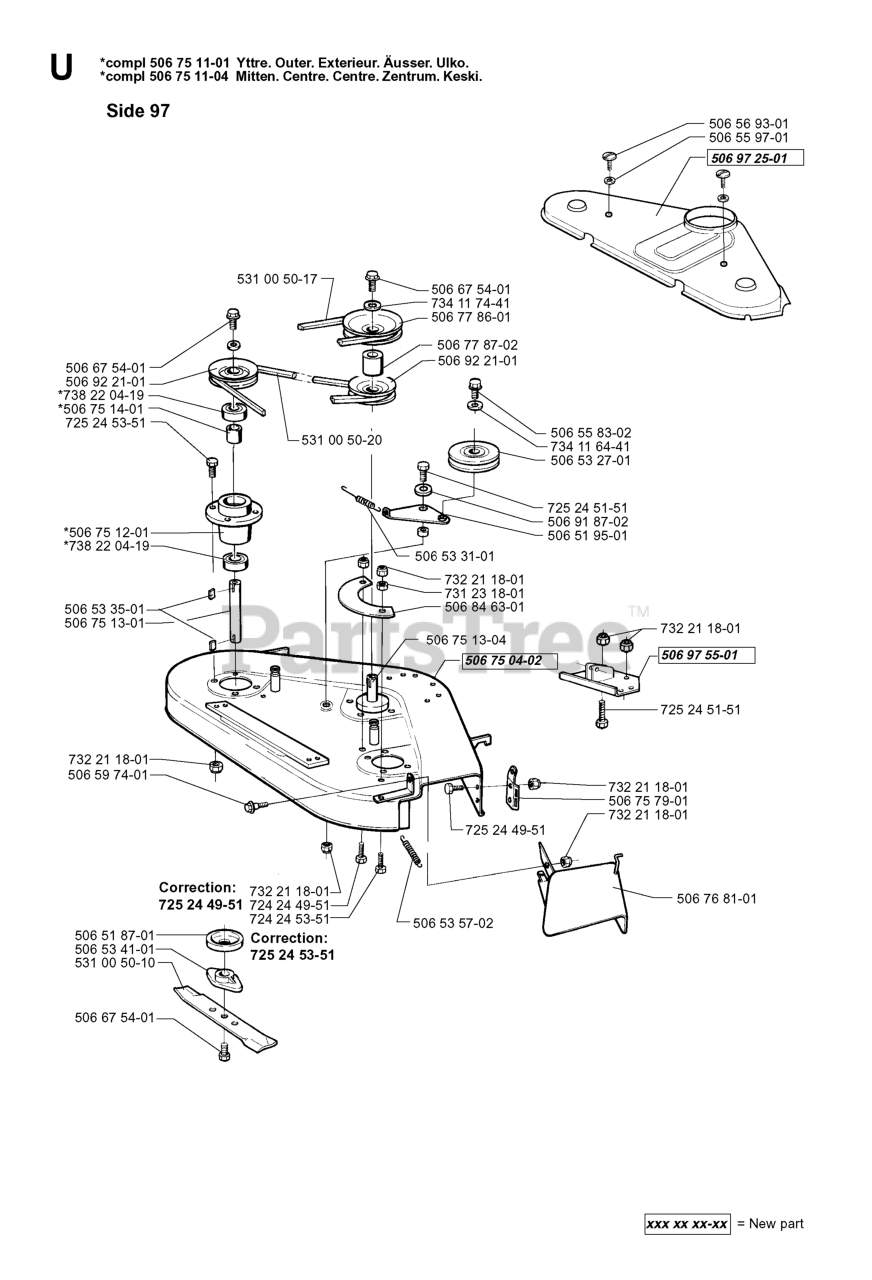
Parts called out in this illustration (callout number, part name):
1	DECK ASM MWR 50VT
2	LOCKNUT
3	BOLT.CARR.SQNK.5/16-18UNC.X3/4
4	RUNNER-LH M
5	BRACKET SWAY BAR
6	RETAINER-SPRNG RB
7	REAR SUSP ARM
8	BLADE BOLT
9	LOCKWASHER
10	WASHER.BLADE
11	BLADE.50".HI-LIFT
12	BEARING.BALL.#6204.(MANDREL)
13	SHAFT.ASM.W/BEARING
14	HOUSING.MANDREL.44/46" VENT
16	STRIPPER
17	ROD-HINGE T
18	Washer 11/32 x 5/8 x 16 Ga SD
19	CAP-SLEEVE LT
20	SPRING TORSION
21	BRACKET, DEFLECTOR
22	NUT PUSH M
23	SHIELD.DEFLECTOR.MOWER.50"BLK.
25	WASHER M
27	WASHER
28	IDLER SPRING SPACER
29	NUT
30	SCREW
31	NUT
32	PULLEY/MANDREL
33	WASHER
34	BOLT.3/8-14X1.25
36	BOLT D
37	STIFFENER ARM
38	KEEPER
39	FLAT IDLER PULLEY
40	PULLEY.DRIVEN.44"
42	RP BOLT 5/16-18 X3/4 ZN/YEL GR
43	ARM.IDLER.SEC.44"
44	SPACER RETAINER
46	BOLT
47	COVER MANDRELL
48	SCREW.1/4-20X5/8
49	COVER.MANDREL.LH.44"
50	ARM.IDLER.PRIMARY
51	SPRING.SEC.44"VEN
52	PULLEY IDLER
53	SHIELD IDLER
54	V-BELT.PRMRY 46/50 VENT.BLK BK
55	BELT V SECONDARY
57	BAR.ASM.GUAGE.WHEEL
58	WHEEL GAGE DONUT
59	BOLT, SHOULDER
60	PIN.CLEVIS
61	BRACKET.GUAGE.WHEEL
62	HARDENED WASHER
63	BOLT.3/8-16X1.50
64	WASHER.5/16.FLAT.STE.STD.
65	PULLEY IDLER FLAT
66	KEEPER
67	LOCKNUT
94	BOLT
95	BRACKET LH (A)
96	BRACKET RH (B)
97	Washer 1 17/32 X 7/8 X 16 Ga
98	NOSE ROLLER
102	WASHER FELT
